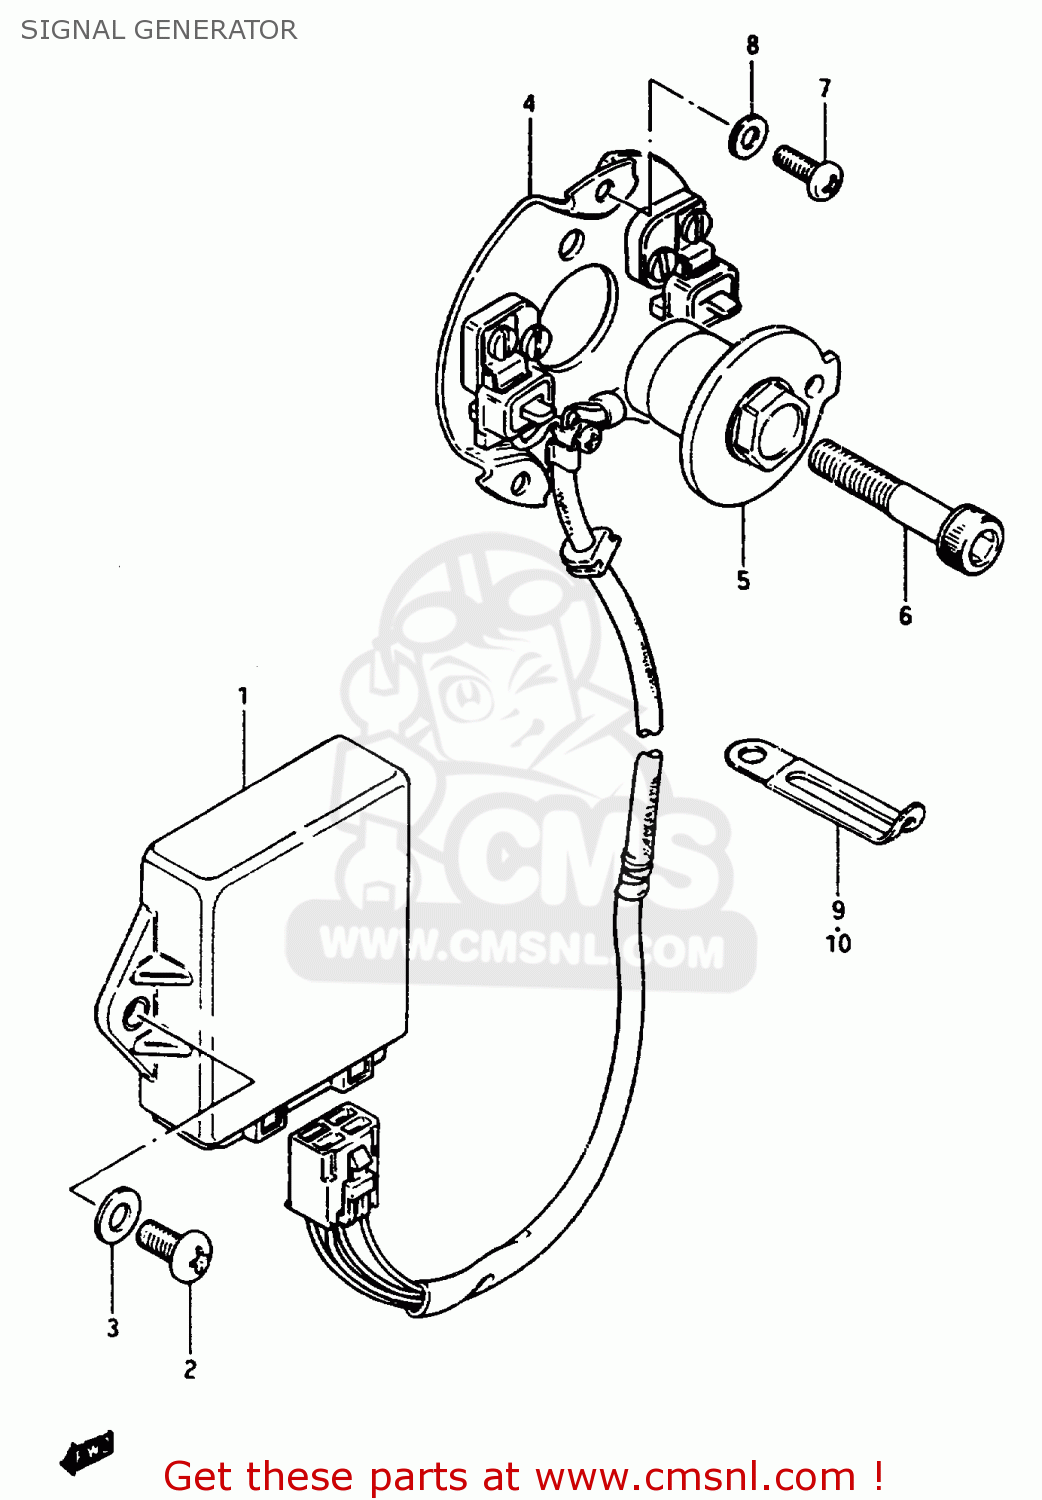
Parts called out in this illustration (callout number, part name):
1	IGNITER UNIT ASSEMBLY
2	SCREW
3	WASHER, LOWER
4	STATOR,SIGNAL GENERATOR
5	ROTOR COMP,SIGNAL
6	BOLT
7	SCREW(5X12)
8	WASHER(5.5X10X0.8)
9	CLAMP L:35
10	CLAMP
